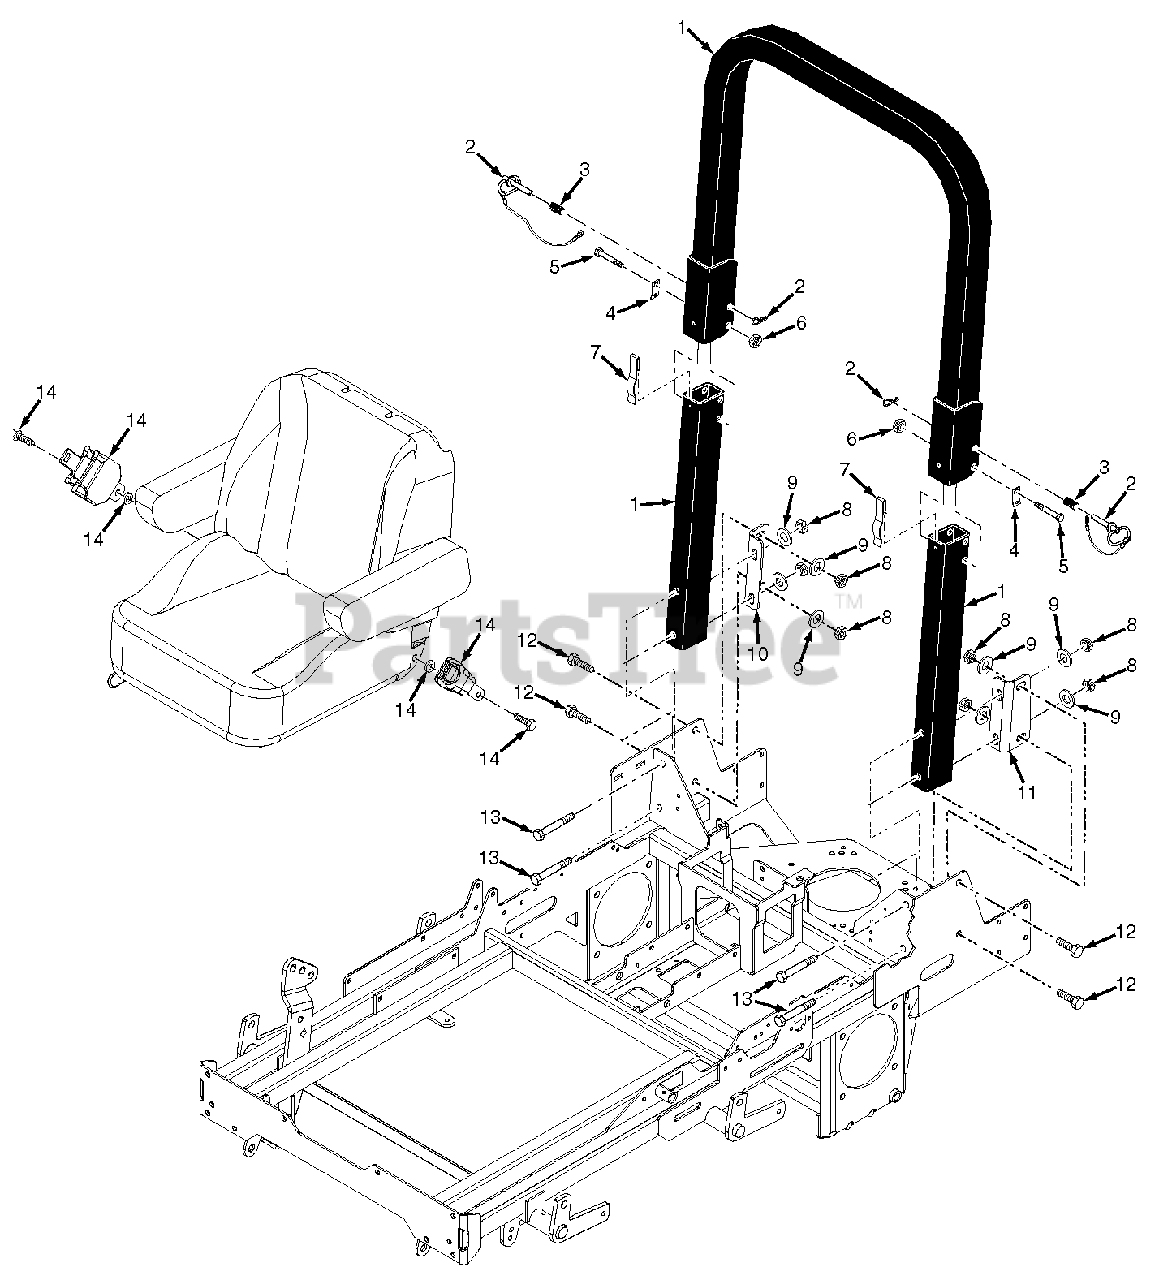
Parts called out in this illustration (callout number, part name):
1	Seat Assembly - SCZ
2	Armrest Kit, LH
3	Seat Belt Kit
4	Recliner Knob
5	Armrest Kit, RH
6	Back Cover
7	Seat Switch
8	Track Kit
9	Cushion Cover
